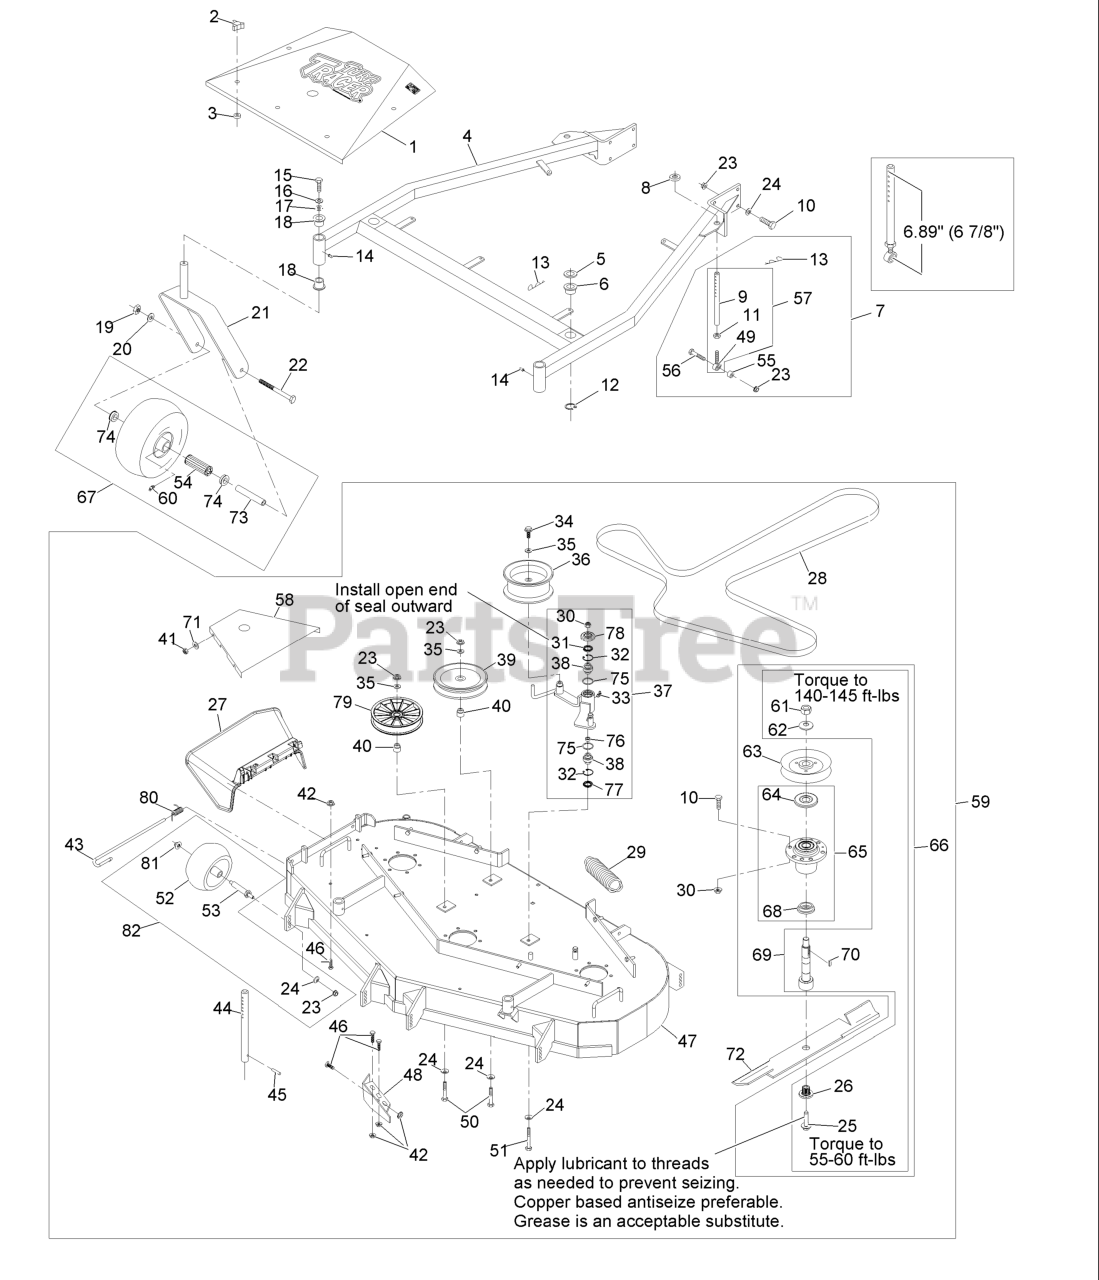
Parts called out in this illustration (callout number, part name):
1	ASM,SHIELD W/DECALS 52 TT
2	KNOB-3 PRONG
4	SUPPORT,DECK W/BUSHINGS
5	SPACER-DECK SUPPORT
6	BUSHING-DECK
7	KIT,SUPPORT LINK W/PIN
9	LINK,SUPPORT
10	SCREW-HH
11	NUT-HJ
12	RING-RETAINING
13	PIN,HAIR COTTER
14	FITTING-GREASE
15	SCREW-HH
16	WASHER-LOCK
18	BEARING-FLANGED
19	NUT-HH
20	WASHER-LOCK
22	SCREW-HH
23	NUT-HHF, WHIZ
24	WASHER-BELLEVILLE
25	SCREW,SEMS 1/2-20 X 2.19
26	BUSHING,SPLINED
27	CHUTE DEFLECTOR XRK M056
28	BELT,DECK DRIVE
30	NUT-LOCK, NI
31	SEAL-LIP, SINGLE
32	RING-SNAP
33	FITTING-GREASE, 90 DEG
34	SCREW-HHF
35	WASHER-FLAT
37	KIT, DECK IDLER TTHP48&52
38	BEARING-SPHERICAL
39	PULLEY-IDLER
40	BUSHING-IDLER
41	NUT-LOCK, NI
43	PIN-CHUTE
44	ROD,DECK SUPPORT
46	SCREW-HH
47	ASM,DECK W/DECALS TTHP52
48	Baffle, Discharge
49	BALLJOINT
50	SCREW-HH
51	SCREW-HH
52	ROLLER-SCALP, ANTI
54	BEARING
56	SCREW-HH
58	SHIELD,SIDE BELT 52
59	Asm, Deck Complete
60	FITTING-GREASE
63	SHEAVE,W/HUB 5.72
64	GUARD-BEARING, TOP
65	KIT, CUTTER HOUSING
66	ASM, CUTTER HSG
67	KIT, SP CASTER WHEEL REPL
68	SPACER-GUARD, BOTTOM
69	KIT, SPLINED SPINDLE 103-
70	KEY-RECTANGLE
71	WASHER-FLAT
74	BUSHING
77	SEAL-LIP, DOUBLE
78	GUARD-TOP
79	PULLEY,IDLER 5"
80	SPRING, TORSION
81	Nut-Nyloc 3/8-16 Flg
